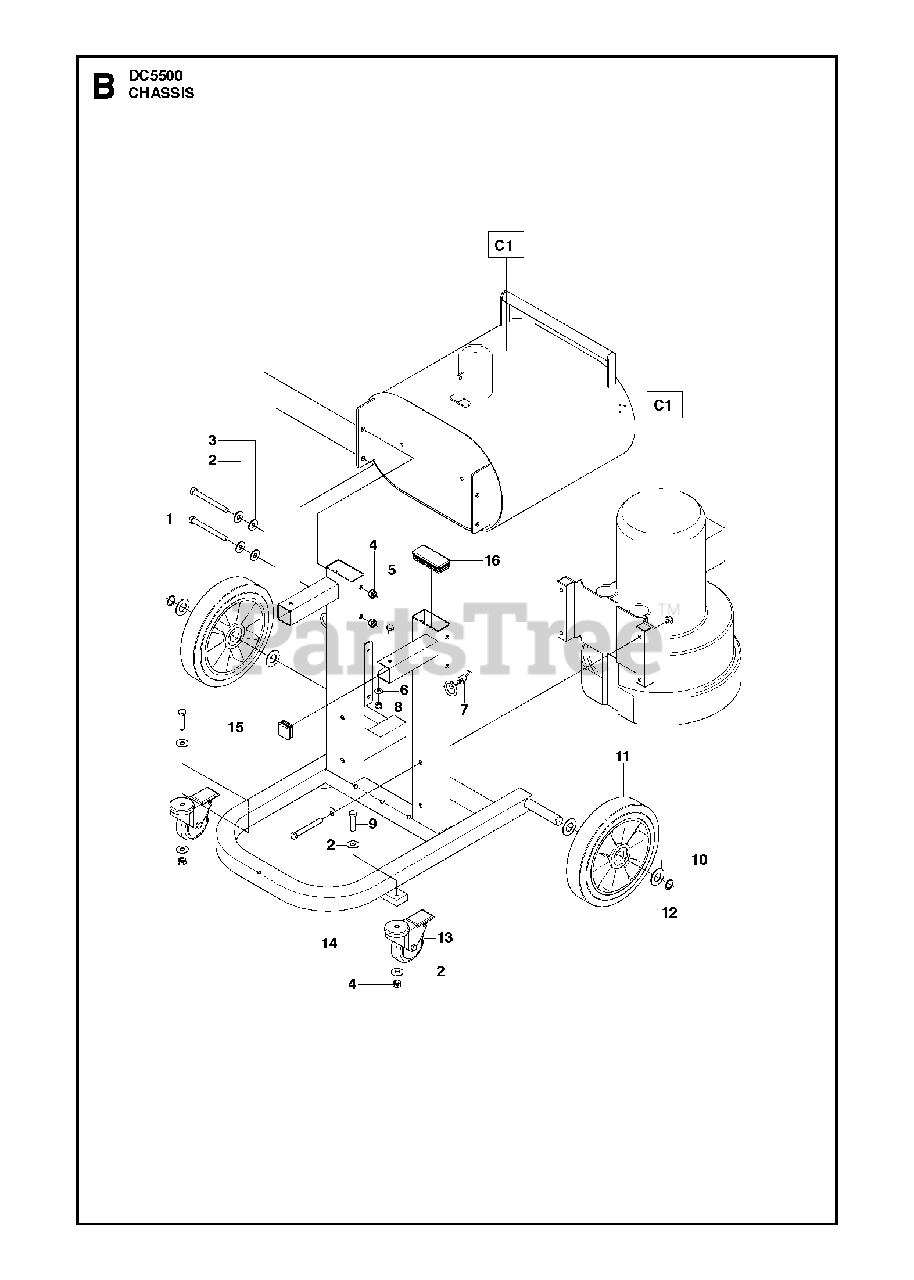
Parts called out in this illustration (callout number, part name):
2	WASHER
6	WASHER
8	HEXAGON LOCKING NUT
